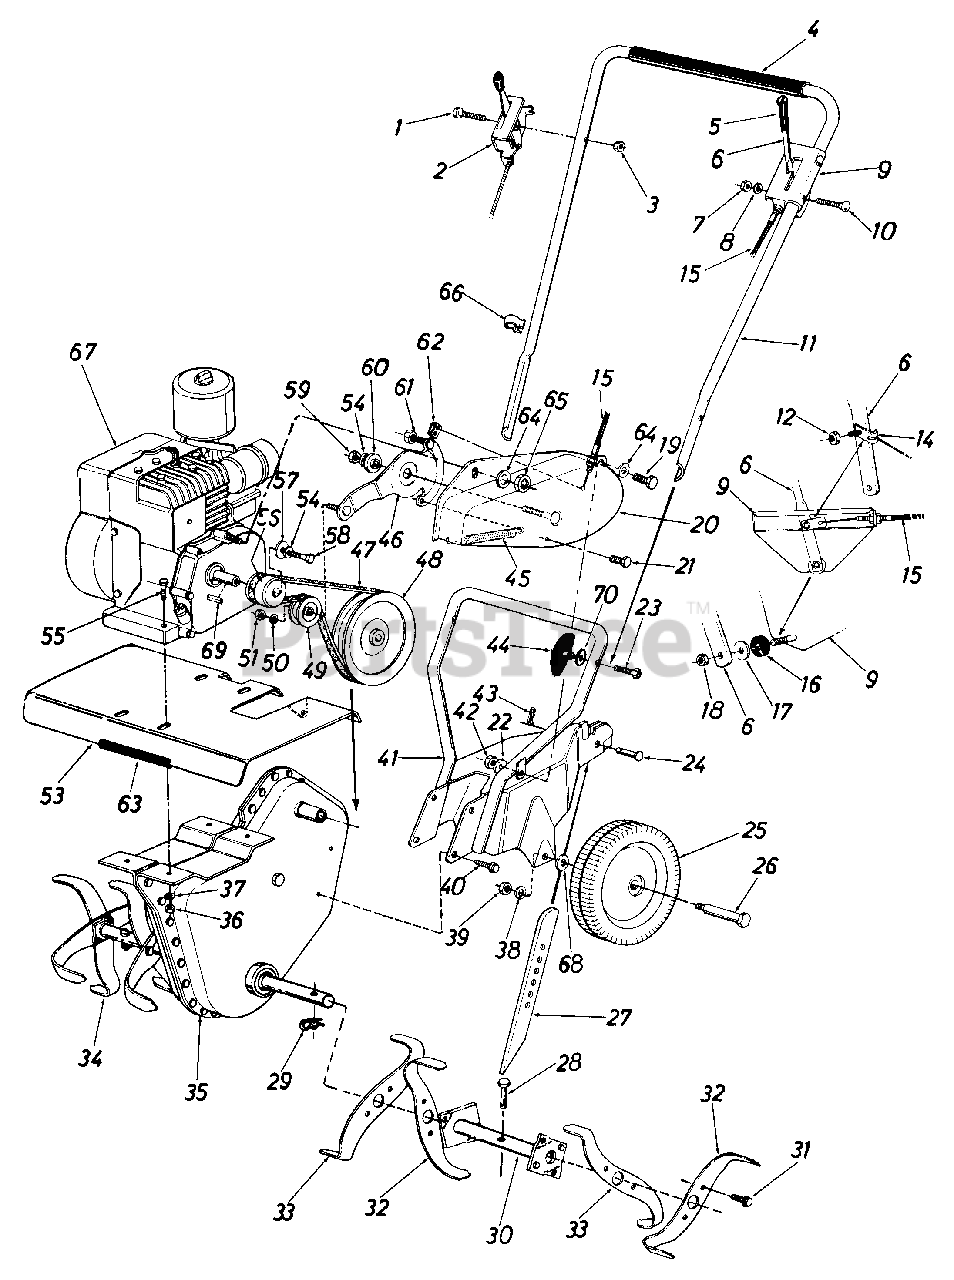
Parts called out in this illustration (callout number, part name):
1	SCREW-HEX 1/4-20 X 1.50
2	CONTROL-THROTTLE
3	NUT-HEX CENTER L-1/4-20
4	GRIP-SHRINK-25 IN
5	GRIP-BLACK
6	HANDLE ASSY-CLUTCH
7	NUT-HEX CENTER L-1/4-20
8	WASHER-FL-.281 ID X .50 OD X .063
9	BRACKET-CLUTCH HDLE
10	BOLT-CARRIAGE 1/4-20 X 1.25
11	HANDLE-UPPER
12	NUT-HEX CENTER L-1/4-20
14	FITTING-CLEVIS LANYARD
15	CABLE-CLUTCH
16	WASHER-RUBBER
17	NUT-HEX CENTER L-1/4-20
18	NUT-HEX CENTER L-1/4-20
19	SCREW-HEX 1/4-20 X .75
20	COVER ASSY-BELT
21	SCREW-HEX WASH SF TAPP
22	LOCK WASHER 1/4 DIA
23	BOLT-CARRIAGE 5/16-18 X 1.75
24	PIN-CLEVIS
25	WHEEL ASSY
26	SCREW-SHLD .498 DIA X 1.450 LG THD
27	BAR-DEPTH
28	PIN-CLEVIS
29	PIN-INTERN COT
34	TINE ASSY-COMP
35	CASE ASSY-CHAIN COMP
36	NUT-HEX 5/16-18
37	WASHER-FL-.344ID X .75OD X .250 SP
38	WASHER-HDL 3/8
39	NUT-HEX CENTER L-3/8-16
40	SCREW-HEX WASH SF TAPP
43	PIN-INTERN COT-5/16 DIA
44	KNOB-HANDLE ASSY
45	SPRING-EXTENSION
46	ARM ASSY-IDLER
47	BELT-V 3/8 X 29
49	PULLEY-IDLER-FLAT W/FLANGES
50	WASHER-LOCK-5/16
51	NUT-HEX INS L-3/8-24
55	SCREW-HEX 5/16-18 X 1.50
57	WASHER-FL-.385 X 1.00 X .135
58	BOLT-3/8 NF X 1"GR5
59	NUT-HEX 5/16-18
60	WASHER-BUSHING
61	NUT-HEX CENTER L-1/4-20
62	FITTING-CLEVIS LANYARD
63	STRIP-TRIM-12IN
64	LOCK WASHER 1/4 DIA
65	NUT-HEX CENTER L-1/4-20
66	TIE-CABLE
68	WASHER-BELL .3/8ID X 1.12OD X .030
69	KEY-SQ 3/16 X .75
70	WASHER-BELL .337 X .867 X .057
